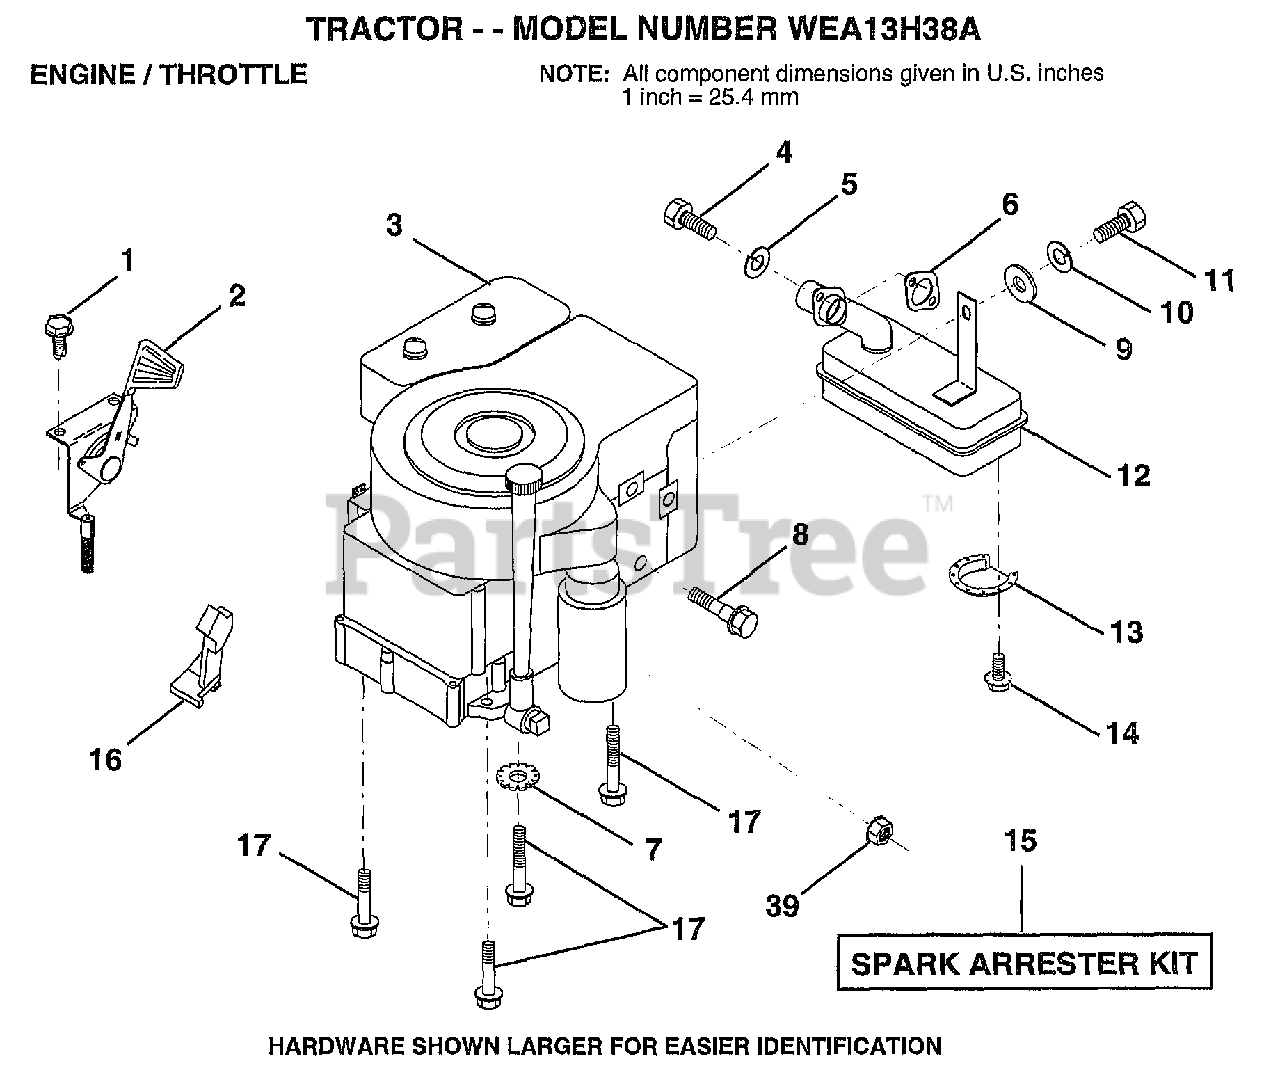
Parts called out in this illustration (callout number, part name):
1	SCREW.1/4-20X1/2
4	SCREW
5	LOCKWASHER
7	LOCKWASHER
8	BOLT T
10	LOCKWASHER
12	MUFFLER
13	DEFLECTOR.222573
16	"STOP,DASH THROTT"
17	SCREW LT
39	NUT
